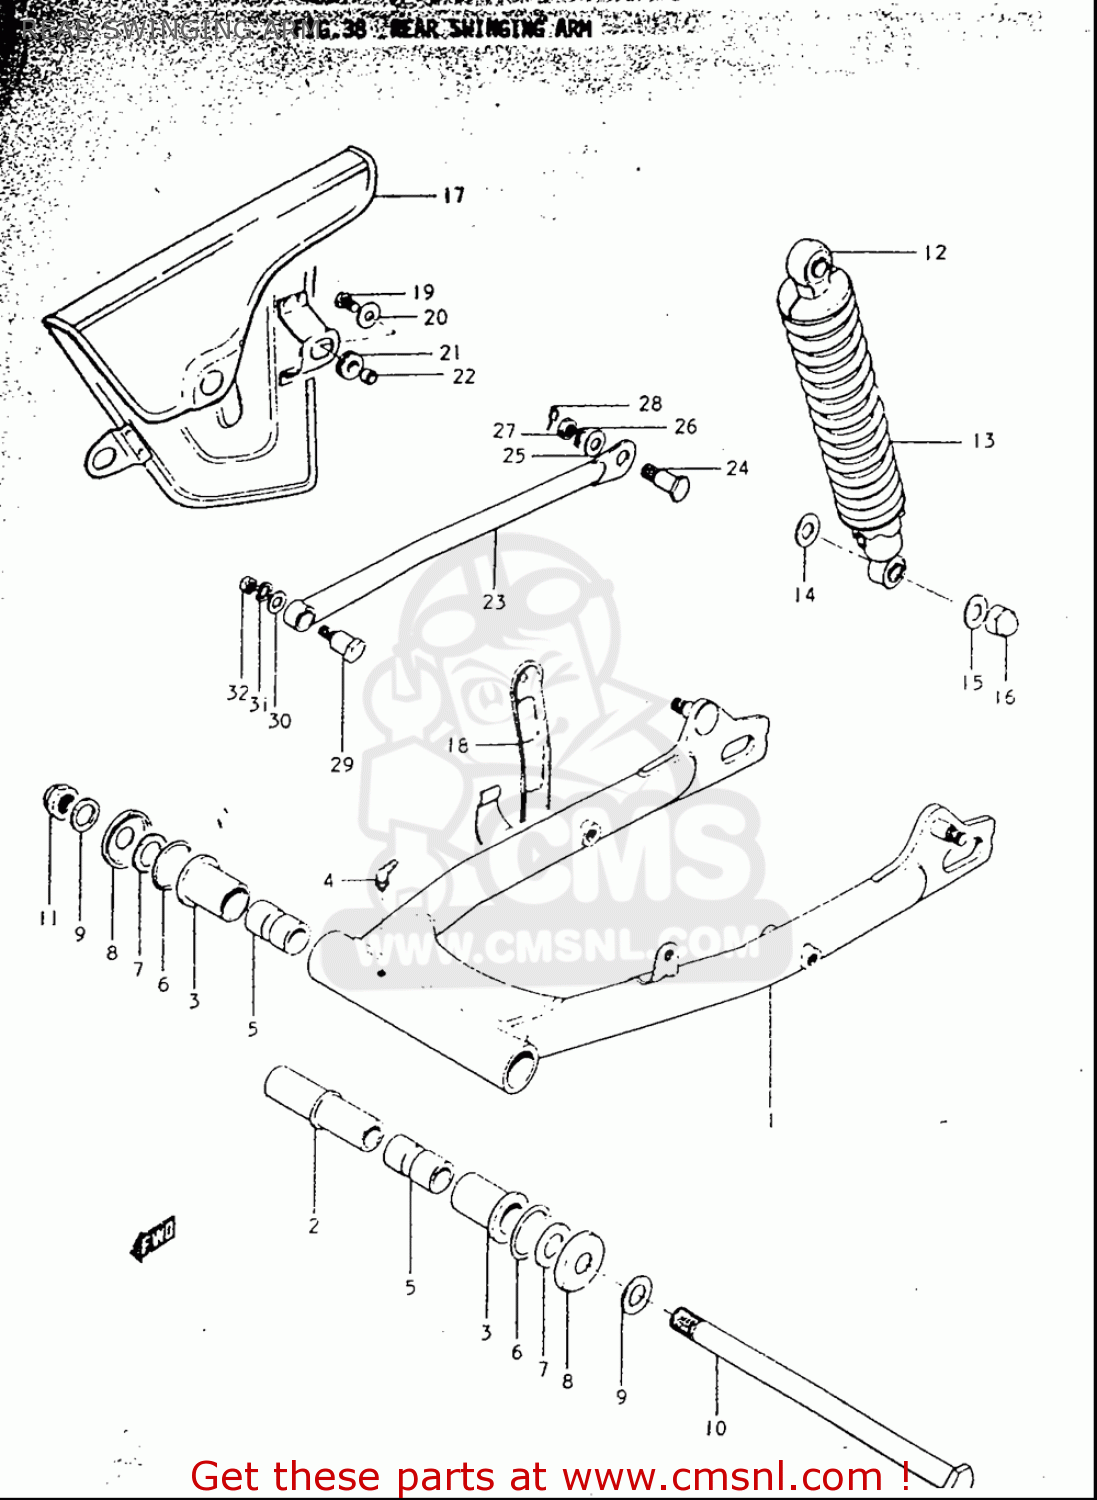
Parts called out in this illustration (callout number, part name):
4	NIPPLE,GREASE
5	SPACER
6	O RING(D:3,ID:29.5)
7	WASHER(14.5X29X2.3)
8	COVER
9	WASHER
14	WASHER
15	WASHER (10.5X24X2.3)
16	NUT
19	SCREW
20	WASHER(6.5X20X1.2)
21	CUSHION
22	SPACER,6.5X9X7
23	TORQUE LINK,REAR
25	WASHER(12.5X24X1.6)
26	WASHER,LOCK
27	NUT
28	SPRING,RETAINER
30	WASHER
31	WASHER,LOCK
32	NUT
